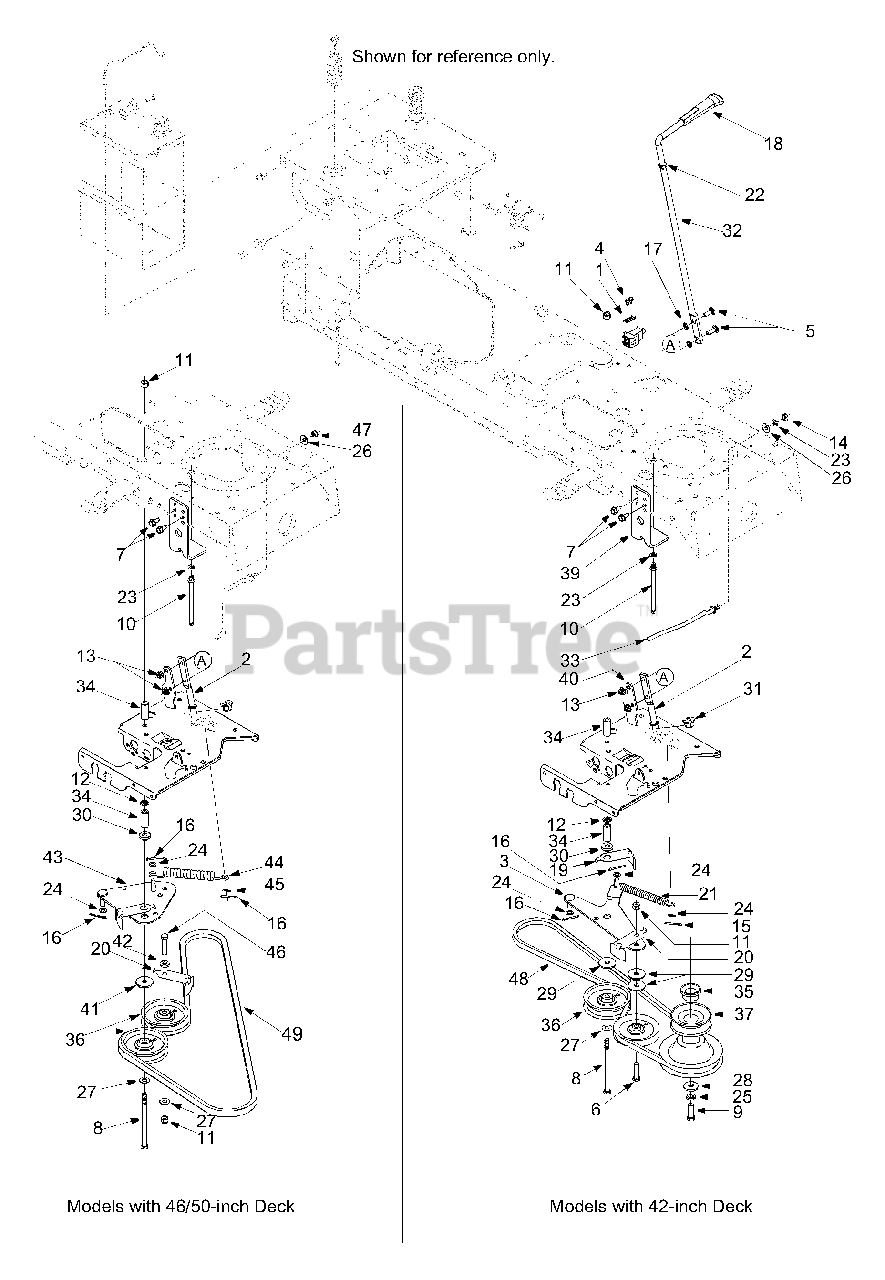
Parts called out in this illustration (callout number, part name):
1	Switch Plate
2	Lever Assembly: PTO Engage
5	Carriage Screw: Special
6	Hex Bolt 3/8-16 x 1.5
7	AB Screw 5/16-12 0.75
8	Hex Bolt 3/8-16 x 5.5
9	Hex Bolt 7/16-20 x 1.25
10	Belt Guard Pin
11	Lock Nut
12	Push Nut
13	Flange Lock Nut
14	Hex Nut 5/16-18
15	Cotter Pin
16	Cotter Pin
17	Speed Nut
18	PTO Knob
19	Belt Guard
20	Belt Guard
21	Extension Spring
22	Flat Washer
23	Lock Washer
24	Flat Washer
25	Lock Washer
26	Bell Washer
27	Flat Washer
28	Flat Washer
29	Flat Washer
30	Spacer
31	Hex Split Flange Bearing
33	Rod: Belt Keeper
34	Spacer
35	Spacer
36	Idler Pulley
37	Engine Pulley 42" deck
37	Engine Pulley 46/50" decks
38	Idler Pulley
41	Flat Washer
42	Flat Washer
44	Extension Spring
45	Flat Washer
46	Hex Bolt 3/8-16 x 1.75
47	Hex Lock Nut 5/16-18
48	V Belt 42'' Deck
49	V Belt 46'' Deck Sec B x 68.24"
49	V Belt 46'' Deck Sec B x 67" models 13AS, 13CS, 13AQ
